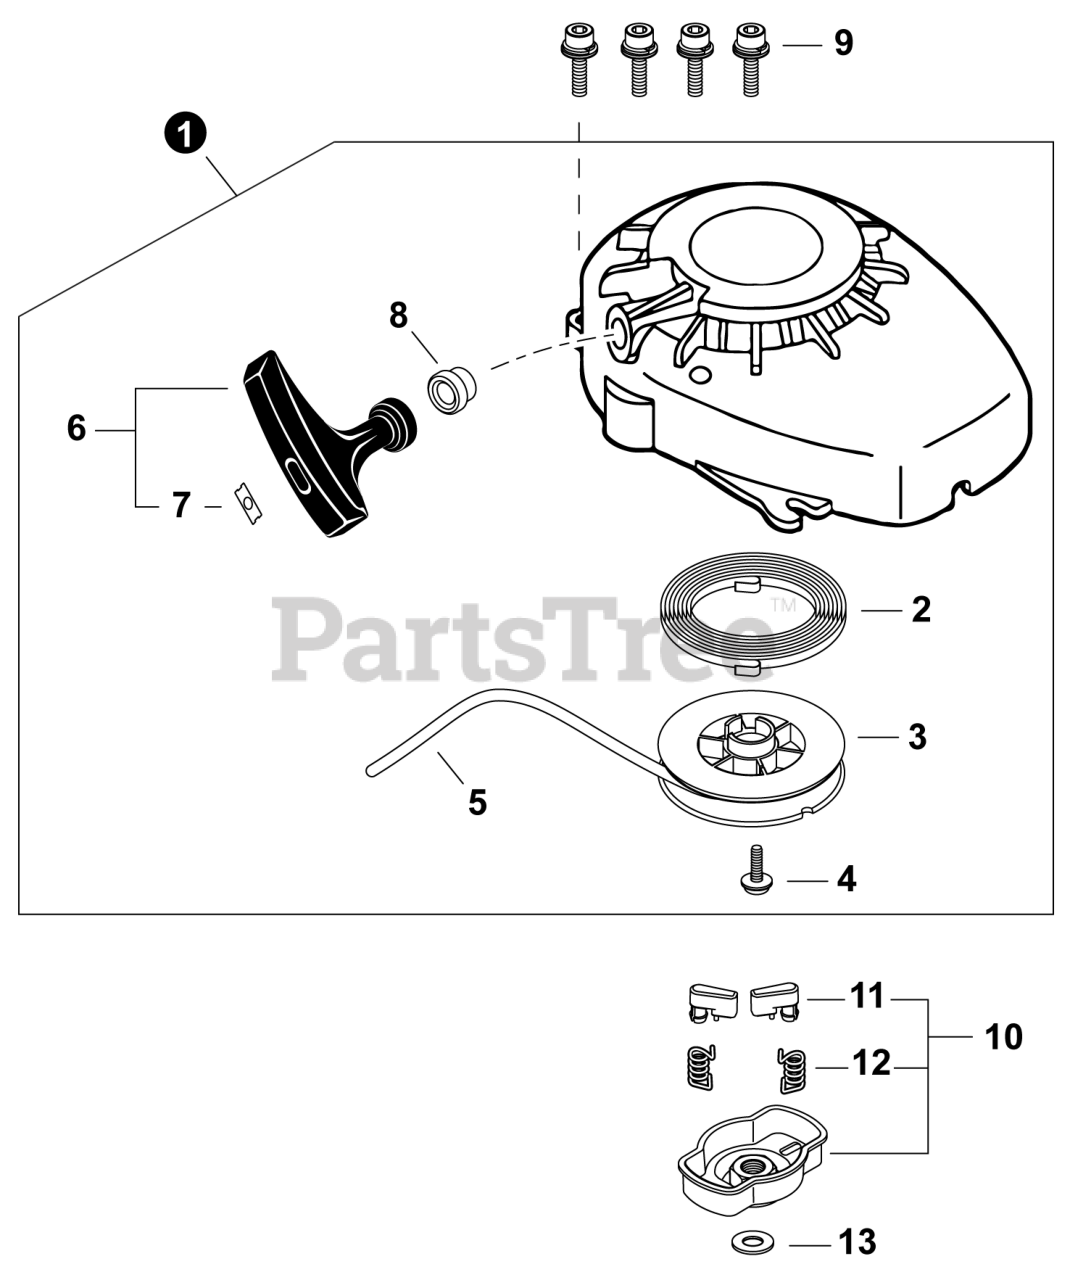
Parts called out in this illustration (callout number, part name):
1	STARTER ASSY, RECOIL
2	SPRING, RECOIL
3	REEL, ROPE
5	ROPE, STARTER
6	GRIP, STARTER
7	RETAINER, ROPE
8	GUIDE, ROPE
9	SCREW 4x16
10	PAWL ASSY, STARTER
11	PAWL, STARTER - BLACK
12	SPRING, RETURN
13	WASHER, SPRING 8
